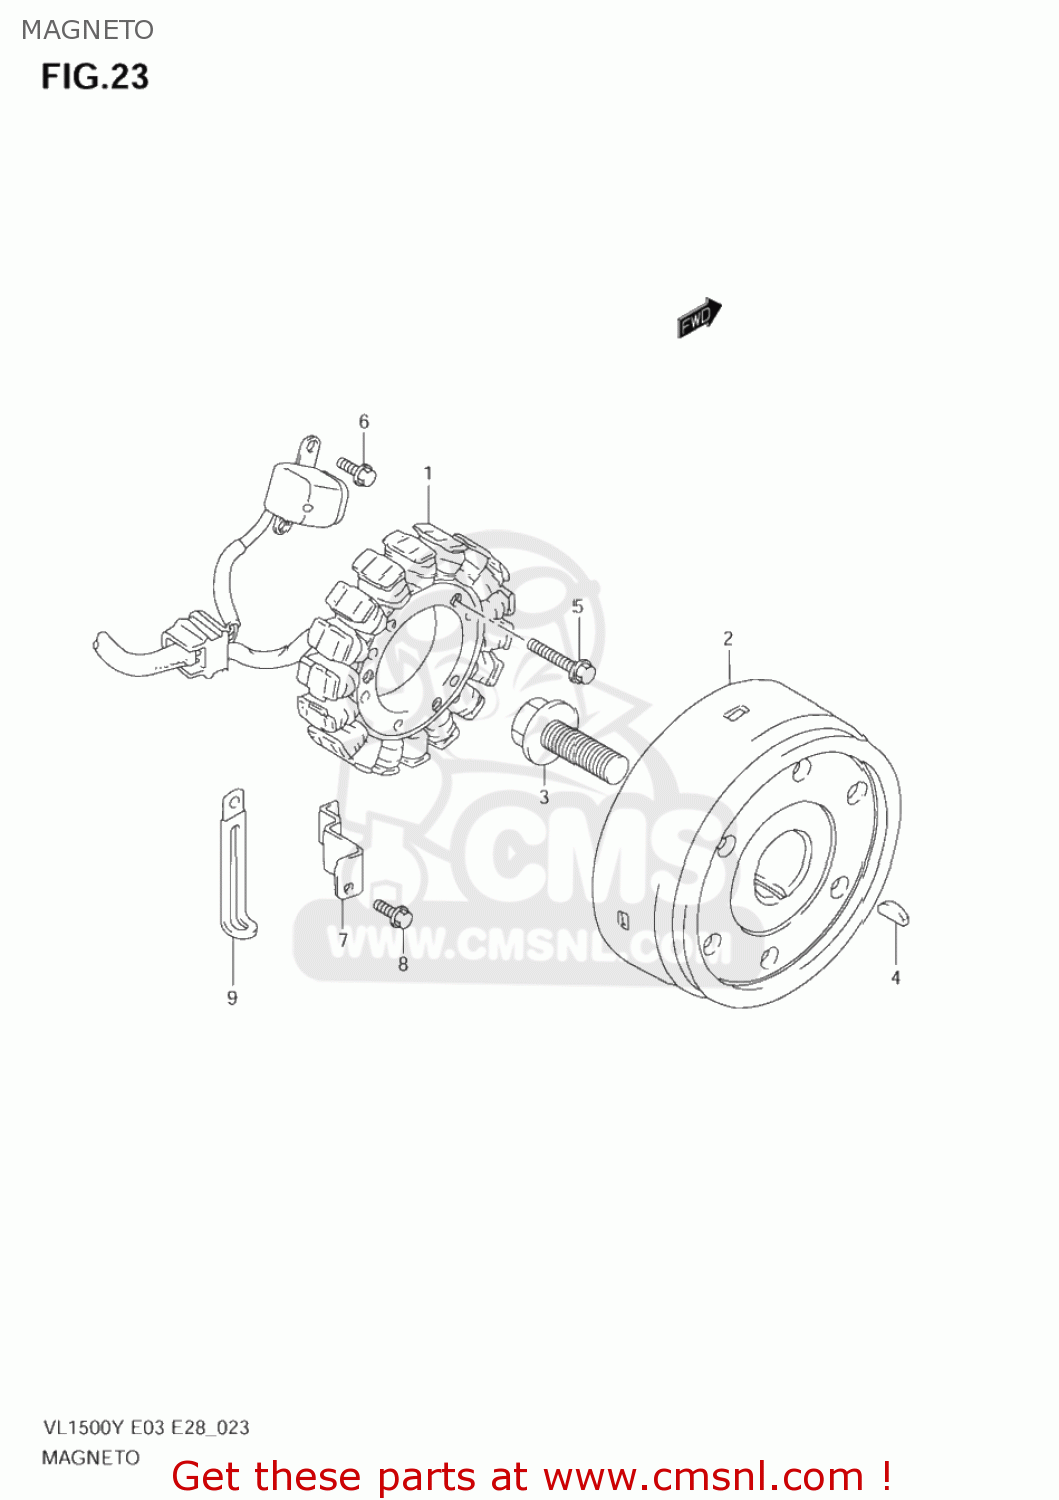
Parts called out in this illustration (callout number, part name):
1	STARTER ASSY
2	ROTOR ASSY
3	BOLT(14X43)
4	KEY
5	BOLT,G/S SWITC
6	BOLT
7	CLAMP,MAGNETO LEAD WIRE
8	BOLT
9	CLAMP(L:45)
